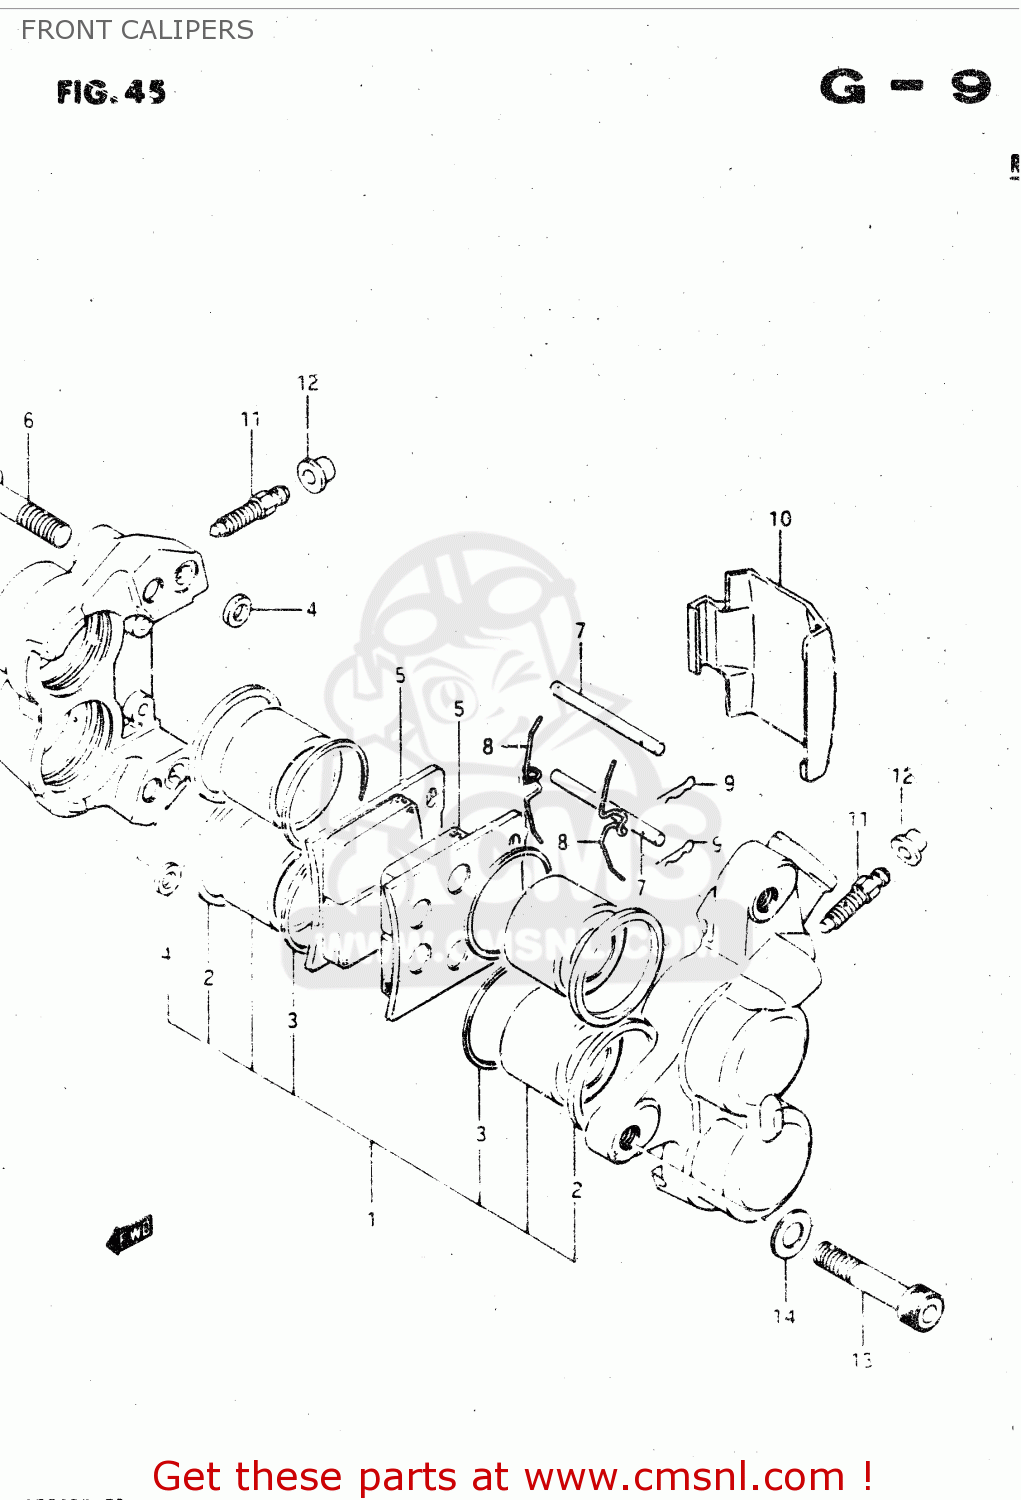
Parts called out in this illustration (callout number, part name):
1	PISTON SET
2	SEAL,PISTON
3	SEAL,WIPER
4	SEAL,JOINT
5	PAD
6	BOLT,HOUSING
7	PIN,PAD
8	SPRING
9	CLIP,PAD PIN
10	COVER,CALIPER
11	BLEEDER
12	CAP,BREATHER
13	BOLT(8X35)
14	WASHER
